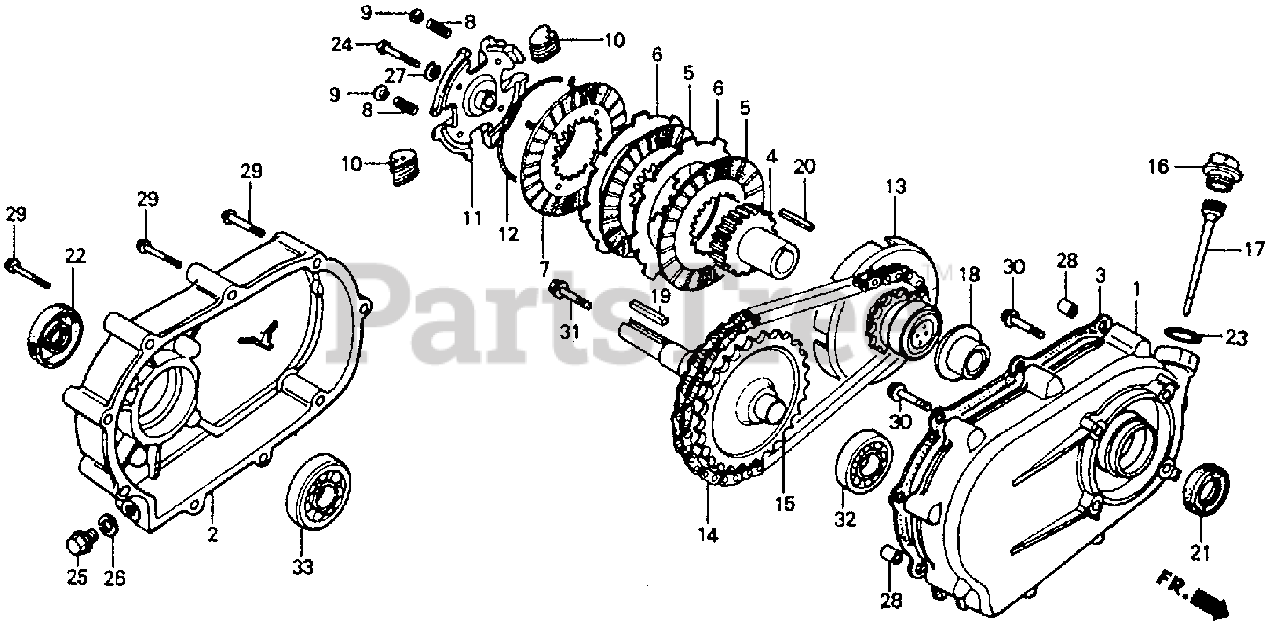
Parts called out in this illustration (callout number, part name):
1	CASE, REDUCTION
2	COVER, REDUCTION
3	GASKET, REDUCTION COVER
4	CENTER, CLUTCH
5	DISK, CLUTCH FRICTION
6	PLATE, CLUTCH
7	PLATE, CLUTCH PRESSURE
8	SPRING, CLUTCH FREE
9	HOLDER, CLUTCH SPRING
10	WEIGHT, CLUTCH
11	HOLDER, CLUTCH WEIGHT
12	CENTER, CLUTCH WEIGHT
13	SPROCKET, DRIVE (14T)
14	CHAIN, DRIVE (RK428SH-36LE)
15	SHAFT, P.T.O. (28T)
16	CAP, REDUCTION OIL
17	DIPSTICK, OIL
18	WASHER, THRUST (25MM)
19	KEY (7X7X33)
20	KEY, CLUTCH CENTER
21	OIL SEAL (30X46X8)
22	OIL SEAL (PJ30507)
23	O-RING (26X2.7)
24	BOLT, HEX. (8X35)
25	BOLT, DRAIN PLUG (12MM)
26	WASHER, DRAIN PLUG (12MM)
27	WASHER, SPRING (8MM)
28	PIN, DOWEL (8X12)
28	PIN A, DOWEL (8X12)
29	BOLT, FLANGE (6X50)
30	BOLT, FLANGE (8X32)
31	BOLT, FLANGE (8X25)
32	BEARING, RADIAL BALL (6205)
33	BEARING, RADIAL BALL (6206)
